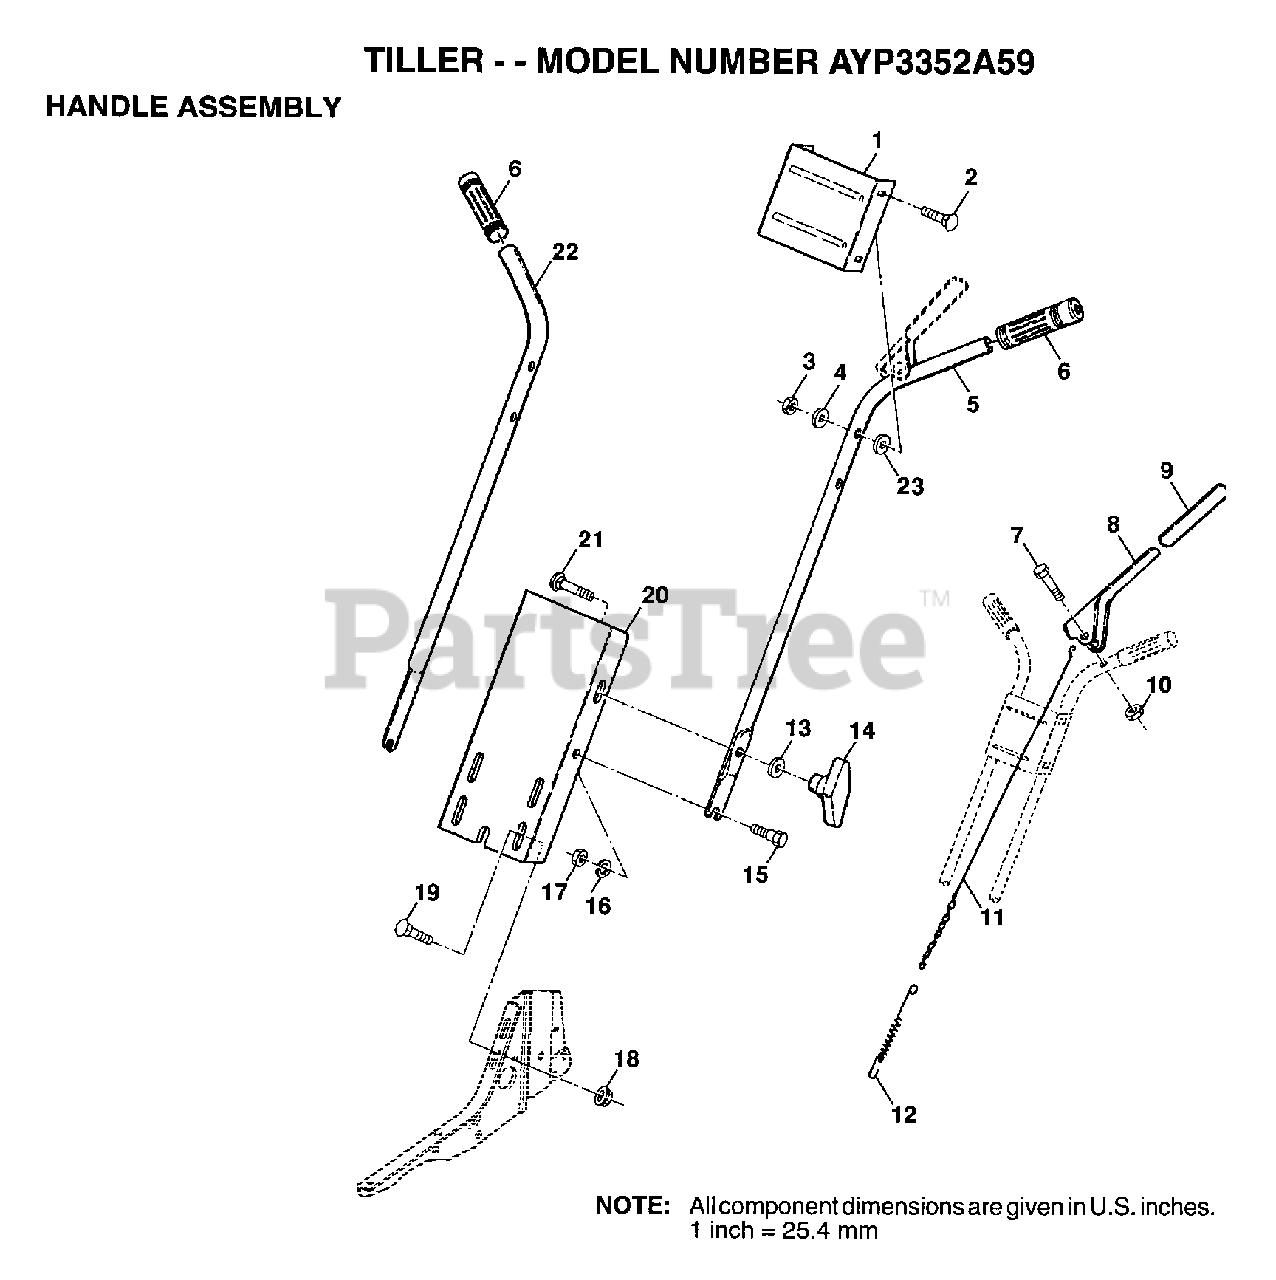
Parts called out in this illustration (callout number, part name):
1	HANDLE BRKT
2	BOLT
4	WASHER
6	GRIP NUB DOUBLE
7	BOLT.HEX.5/16-1.5
9	GRIP T
12	SPRING EXT TI
13	WASHER
14	KNOB HANDLE
16	LOCKWASHER
17	NUT.HEX.5/16-18
18	NUT
19	BOLT
20	PANEL. HANDLE
21	BOLT CRT
23	WASHER
